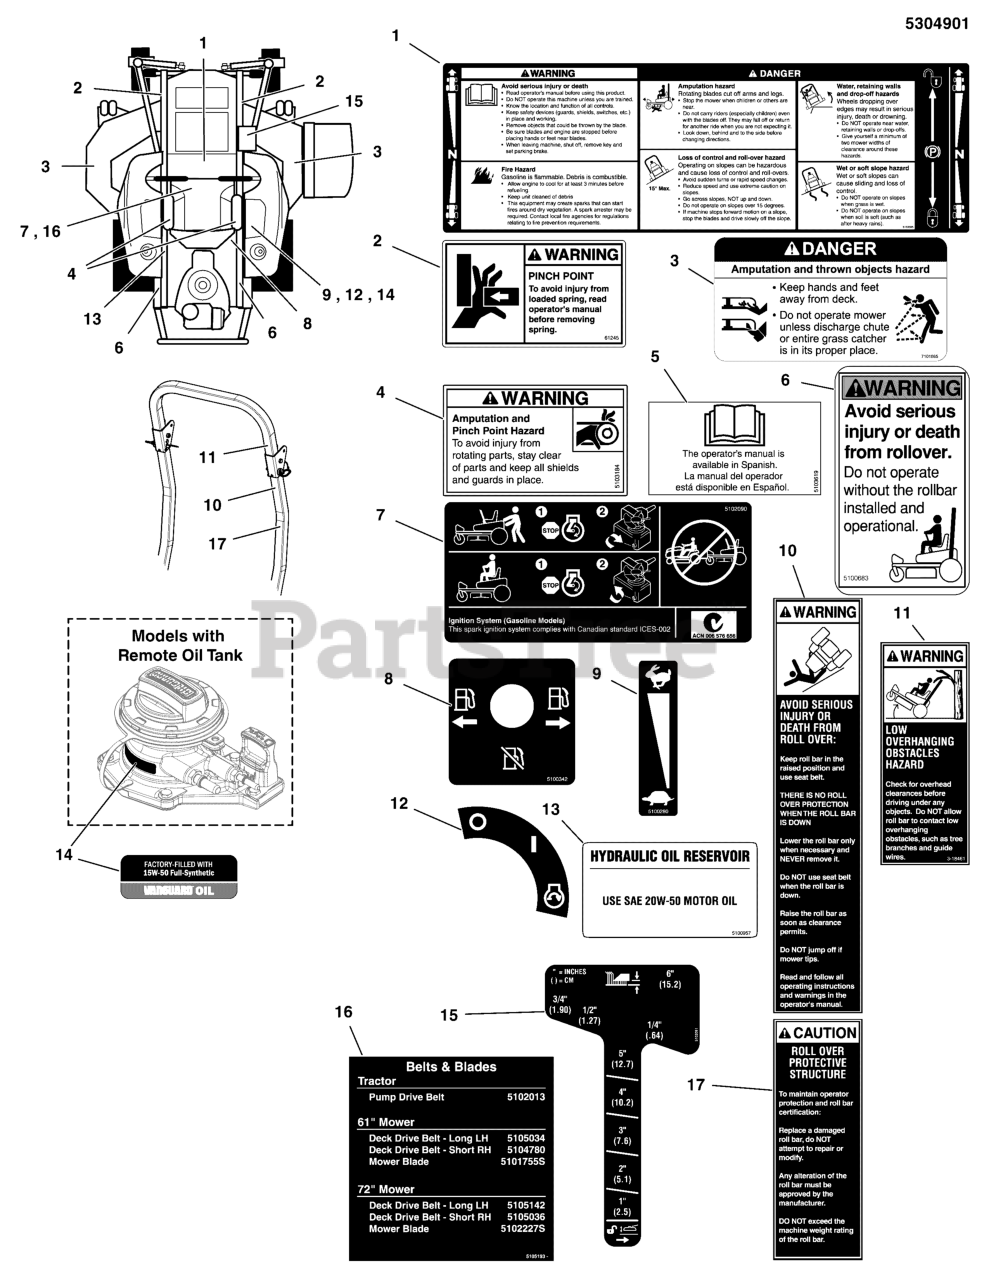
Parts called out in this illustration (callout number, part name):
1	DECAL, MAIN SAFETY
2	DECAL, PINCH POINT
3	DECAL, DANGER DO NOT OPERATE W/O DEFLECT
4	DECAL, WARNING, HAND IN BELT, ENG ONLY
5	DECAL, MANUAL AVAIL IN SPANISH
6	DECAL, WARNING, ROLL BAR
7	DECAL, TRANSAXLE RELEASE, S200XT
8	DECAL, FUEL VALVE
9	DECAL, THROTTLE CONTROL
10	DECAL, WARNING, FOLDING ROPS
11	DECAL, WARNING & CAUTION, ROPS
12	DECAL, IGNITION SWITCH
13	DECAL, HYDRAULIC OIL, 20W50
14	LABEL, OIL INFORMATION
15	DECAL-HEIGHT CITATION
16	DECAL, BELT & BLADE S200XT, F210Z, 2BELT
17	DECAL, CAUTION. FOLDING ROPS
